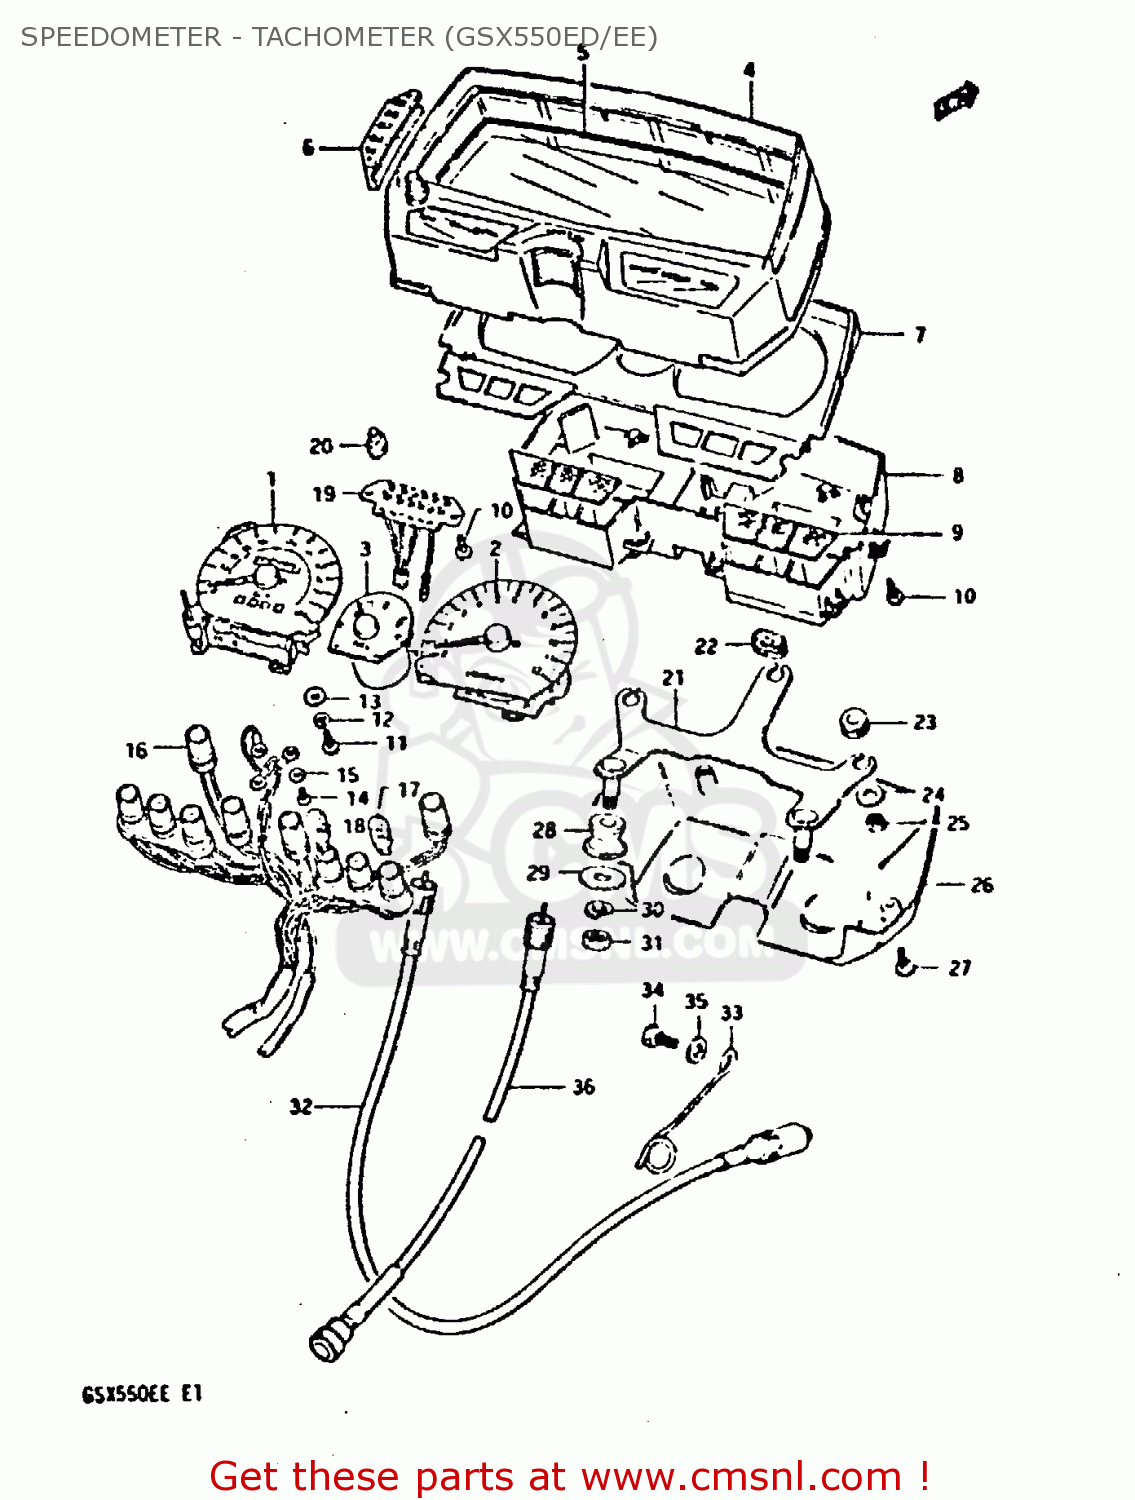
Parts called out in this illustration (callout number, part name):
1	SPEEDOMETER (MILE/KILO)
2	METER,TACHOMETER
3	METER,FUEL
4	HOOD,METER
5	GLASS,SPEEDOMETER
6	CUSHION,METER CASE
7	PLATE,METER WINDOW
8	CASE,METER,INNER
9	LENS SET,PILOT
10	SCREW,GEAR INDICATOR
11	SCREW
12	LOCK WASHER
13	WASHER
14	SCREW
15	WASHER
16	SOCKET
17	BULB(12V3.4W,T10,BF175-01450A)
18	BULB(12V1.7W,T10,WB121)
19	SOCKET,GEAR INDICATOR
20	BULB(14V1.12W)
21	BRACKET,METER
22	CUSHION,METER
23	CUSHION,METER
24	WASHER,METER
25	NUT
26	COVER,METER,UNDER
27	SCREW
28	CUSHION,METER BRACKET
29	WASHER (8.5X20X1.6)
30	LOCK WASHER
31	NUT
32	CABLE ASSEMBLY,SPEEDOMETER
33	CLAMP,SPEEDOMETER CABLE
34	BOLT, UPPER
35	WASHER
36	CABLE ASSY,TACHOMETER
